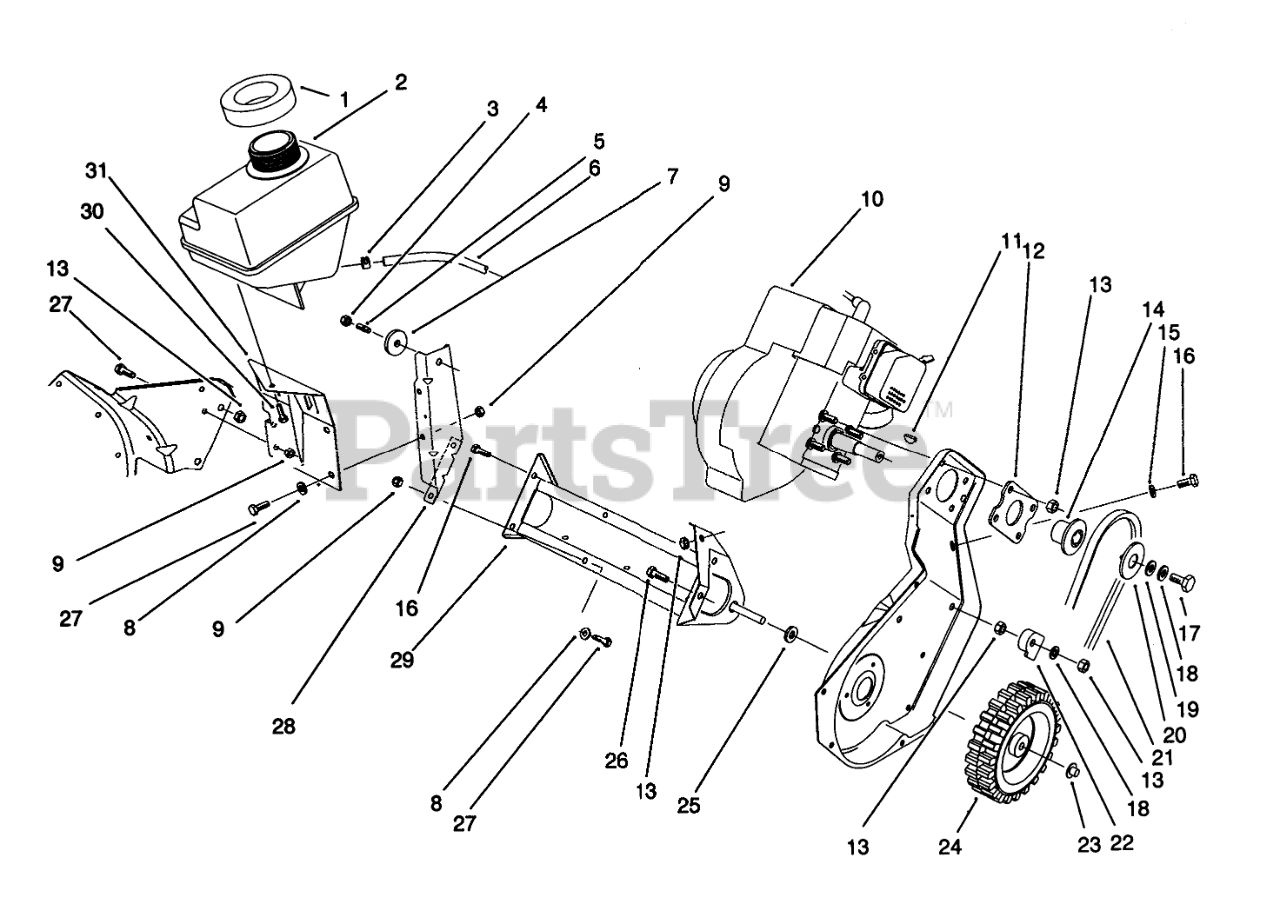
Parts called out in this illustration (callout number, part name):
1	SEAL-FOAM
2	Tank-Gas
3	Clamp
4	NUT-LOCK, NI
6	LINE-FUEL
7	WASHER-SUPPORT, ENGINE
8	WASHER-FLAT
9	NUT-LOCK, NI
11	KEY-WOODRUFF
12	Plate Engine
13	NUT-LOCK, NI
14	Hub-HALF SHEAVE
15	WASHER-PLAIN
16	SCREW-HH
17	SCREW-HH
18	WASHER-BELLEVILLE
19	WASHER-FLAT
20	CAP-HALF SHEAVE
21	Belt-Drive
22	GUIDE-CABLE
23	RETAINER-PUSH ON
24	WHEEL
25	SPACER-PLASTIC
26	SCREW-HH
27	SCREW-HH
28	Support-Engine
29	Frame Assembly
30	SCREW-SHWH, THREAD FORMING
31	Bracket-Fuel Tank
